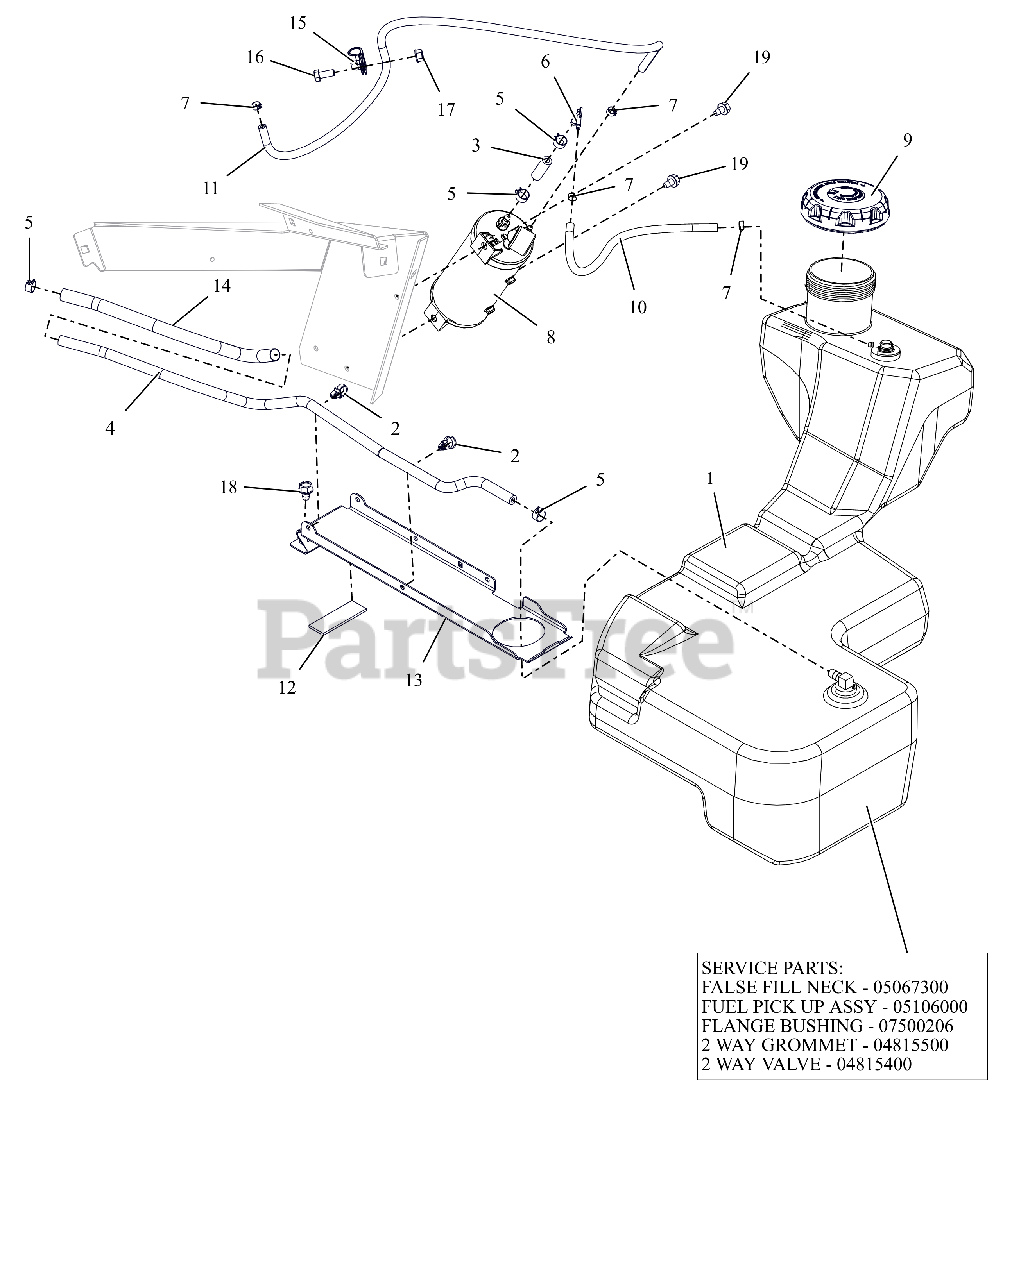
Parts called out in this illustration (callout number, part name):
1	ASM, HD FUEL TANK
1	INSERT, FUEL NECK FALSE FILL
1	ASM, HD FUEL PICK-UP
1	BSHG-FLG .375X1.062X.625 NITR
1	GROMMET, 2-WAY
1	VALVE, 2-WAY
2	ROUTING CLIP (1/2" ID)
3	HOSE, .25 LOW-PERM BULK GAS
4	HOSE, .25 LOW-PERM BULK GAS
5	CLAMP, FUEL LINE
6	FITTING-3/16X1/4 90DEGREE VAC
7	CLAMP-HOSE, SPRING .188
8	CANISTER, 400 CC CARB
9	CAP, FUEL VENTIN AUTOLOCK
10	HOSE, .188 30R7 BULK
11	HOSE, .188 30R7 BULK
12	PAD,RBR 1.0"X3.0" W/ADHESIVE
13	BRKT, FUEL TANK HOLD DOWN
14	SLEEVE, THERMAL 12"
15	CLAMP, CUSHIONED STEEL
16	BLT,HEX .31-18X.75 G5 ZCC
17	NUT,LK-CTR-FLG .31-18 GF ZCC
18	SCR,TAP .375-16X.50 HWH TR ZCC
19	SCR,TAP .312-18X.50 HWH TR ZCC
